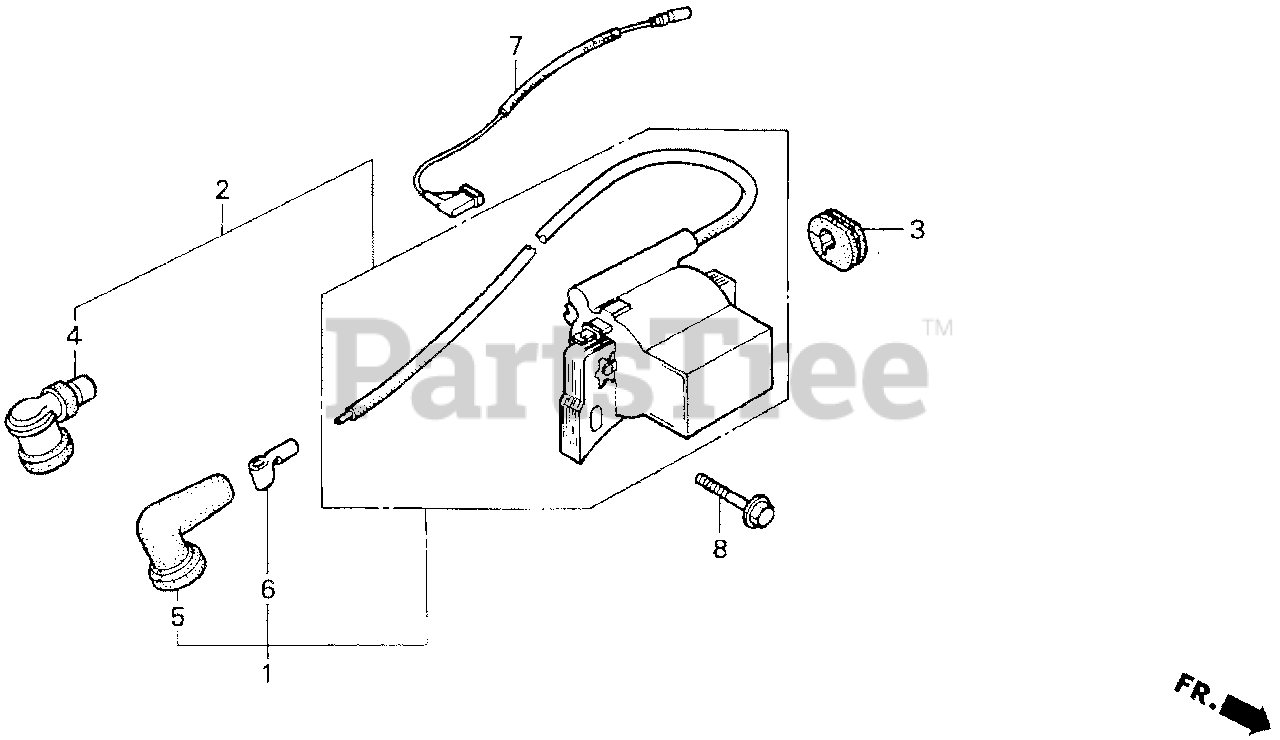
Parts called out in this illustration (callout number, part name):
1	COIL ASSY., IGNITION
3	GROMMET, IGNITION WIRE
5	CAP, IGNITION (TOYO)
6	TERMINAL, PLUG
7	WIRE, STOP SWITCH
8	BOLT, FLANGE (6X25)
